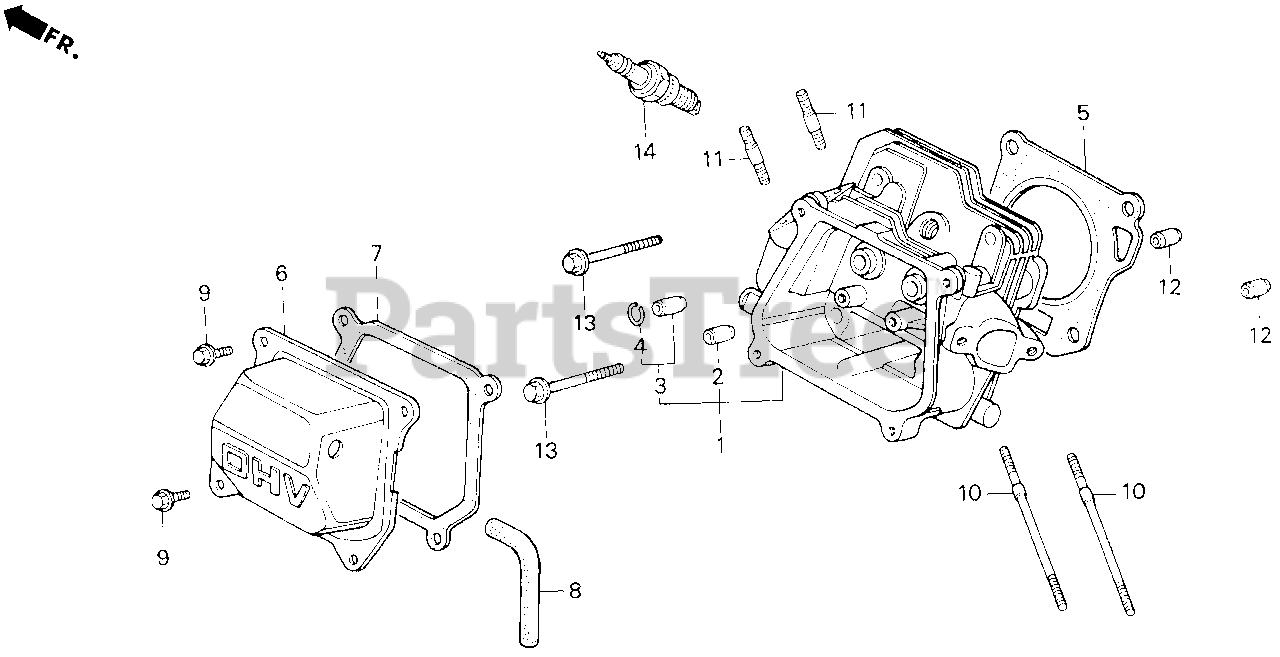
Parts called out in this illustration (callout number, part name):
1	CYLINDER HEAD
2	GUIDE, VALVE (OVER SIZE)
3	GUIDE, EX. VALVE (OVER SIZE)
4	CLIP, VALVE GUIDE
5	GASKET, CYLINDER HEAD
6	COVER, HEAD
7	GASKET, HEAD COVER
8	TUBE, BREATHER
9	BOLT, FLANGE (6X12) (CT200)
9	BOLT, FLANGE (6X13) (CT200)
10	BOLT, STUD (6X112)
11	BOLT, STUD (8X32)
12	PIN, DOWEL (10X16)
13	BOLT, FLANGE (8X60)
14	SPARK PLUG (BPR5ES) (NGK)
14	SPARK PLUG (W16EPR-U) (DENSO)
